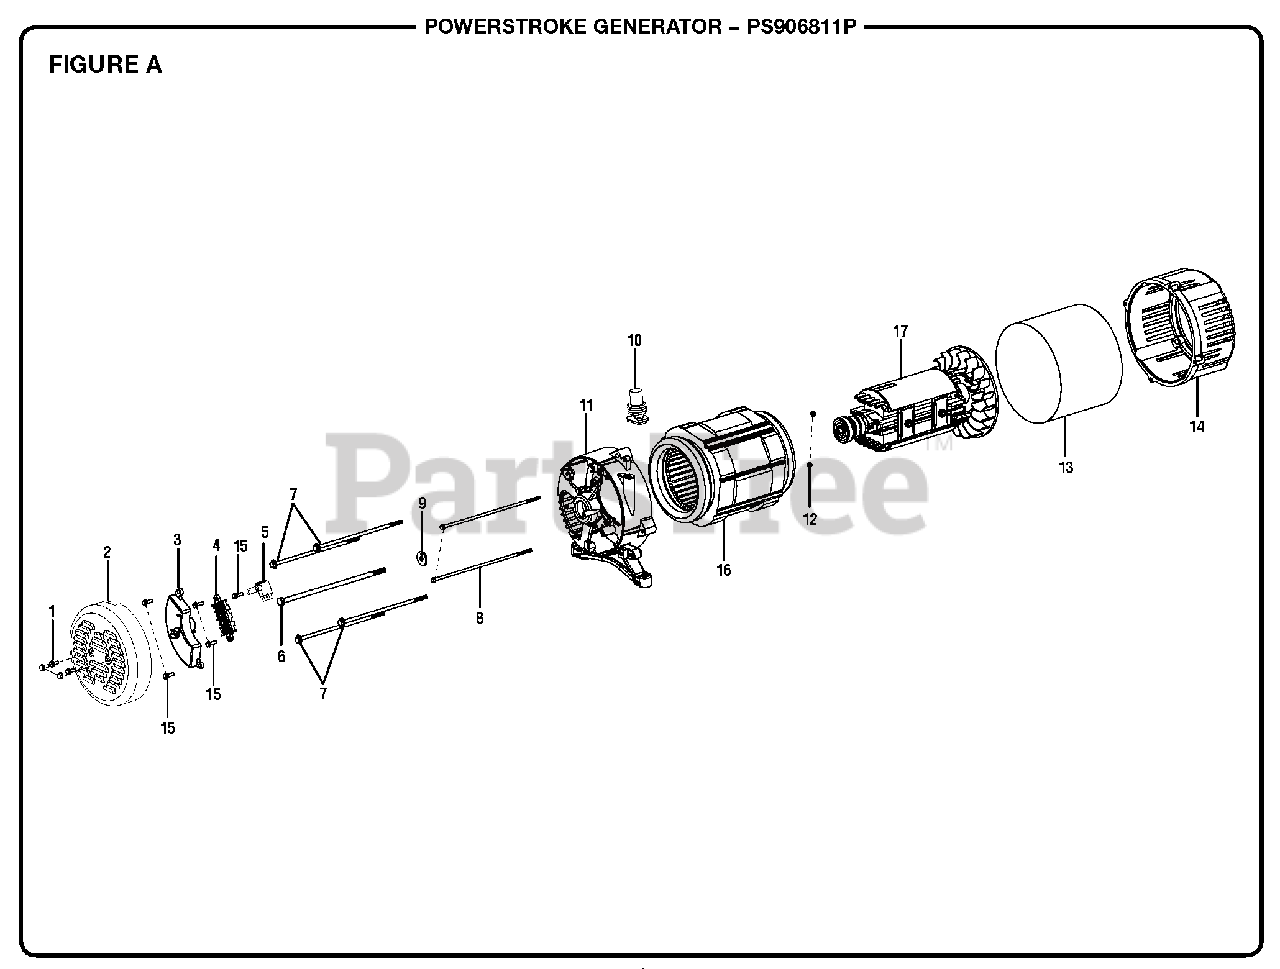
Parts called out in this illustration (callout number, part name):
1	Bolt (M5 x 12 mm, Hex Hd.)
2	Brush Cover
3	Automatic Voltage Regulator
4	Terminal Block
5	Brush Assembly
6	Bolt (5/16-24 x 235 mm, Hex Washer Hd.)
7	Bolt (M6 x 188 mm, Hex Washer Hd.)
8	Bolt (M5 x 210 mm, Hex Washer Hd.)
9	Washer (ID8 x OD26 x 3t)
10	Rubber Boot
11	Bearing Housing
12	Hex Nut (M5)
13	Generator Head Cover
14	Adaptor Housing
15	Bolt (M5 x 16 mm, Hex Hd.)
